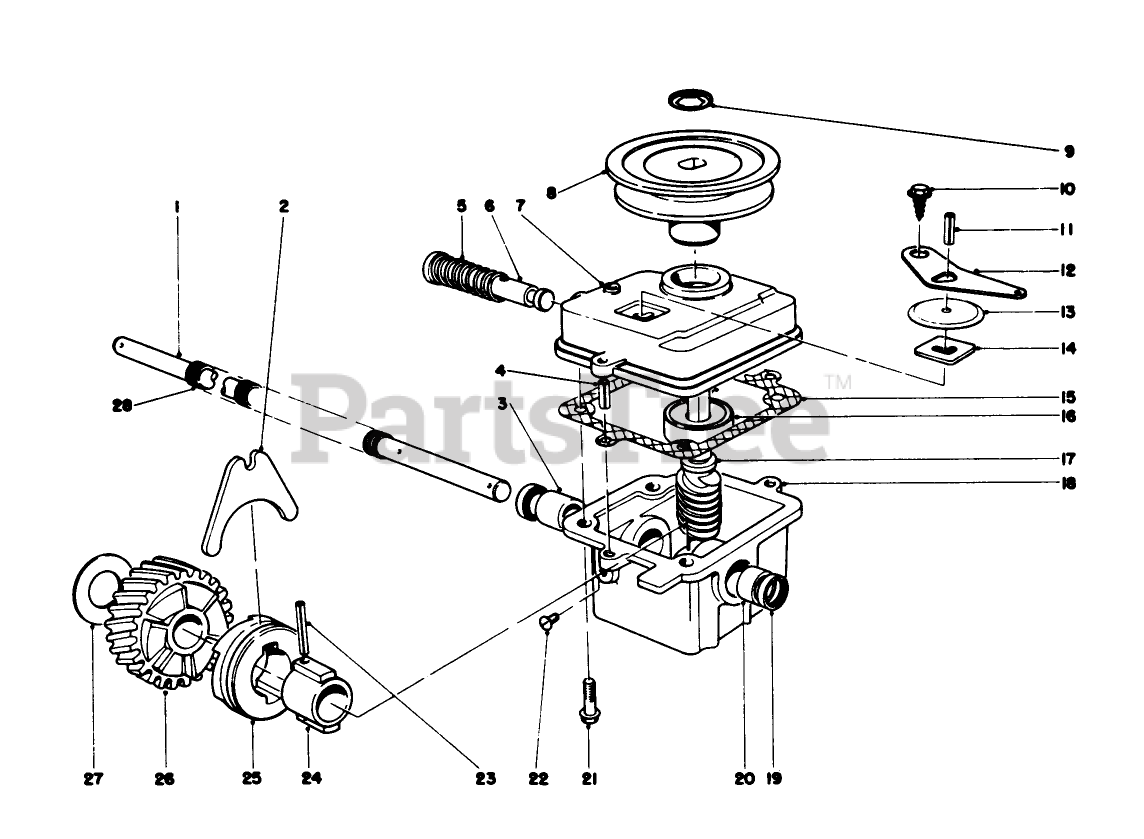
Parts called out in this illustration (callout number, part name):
1	DRIVE SHAFT (SERVCE)
2	SHIFTER FORK
3	Bushing
4	3/16 X 1/2 ROLL PIN
5	SPRING
6	Shift Rod
7	Cover Gear Case
8	PULLEY
9	PUSH-ON 93-3236
10	Screw
11	PIN-ROLL
12	SHIFTER ARM
13	TRANS DUST COVER
14	LATCH PLATE
15	GASKET
16	Bearing
17	Worm Shaft (Incl. Ref. #26)
18	Gear Case (Incl. Ref. #3, 19-20)
19	Seal
20	Bushing
21	Screw
22	NYLON SCREW
23	Pin
24	SLEEVE
25	CLUTCH JAW
26	Helical Gear
27	THRUST WASHER
28	COVER-SHAFT, DRIVE
